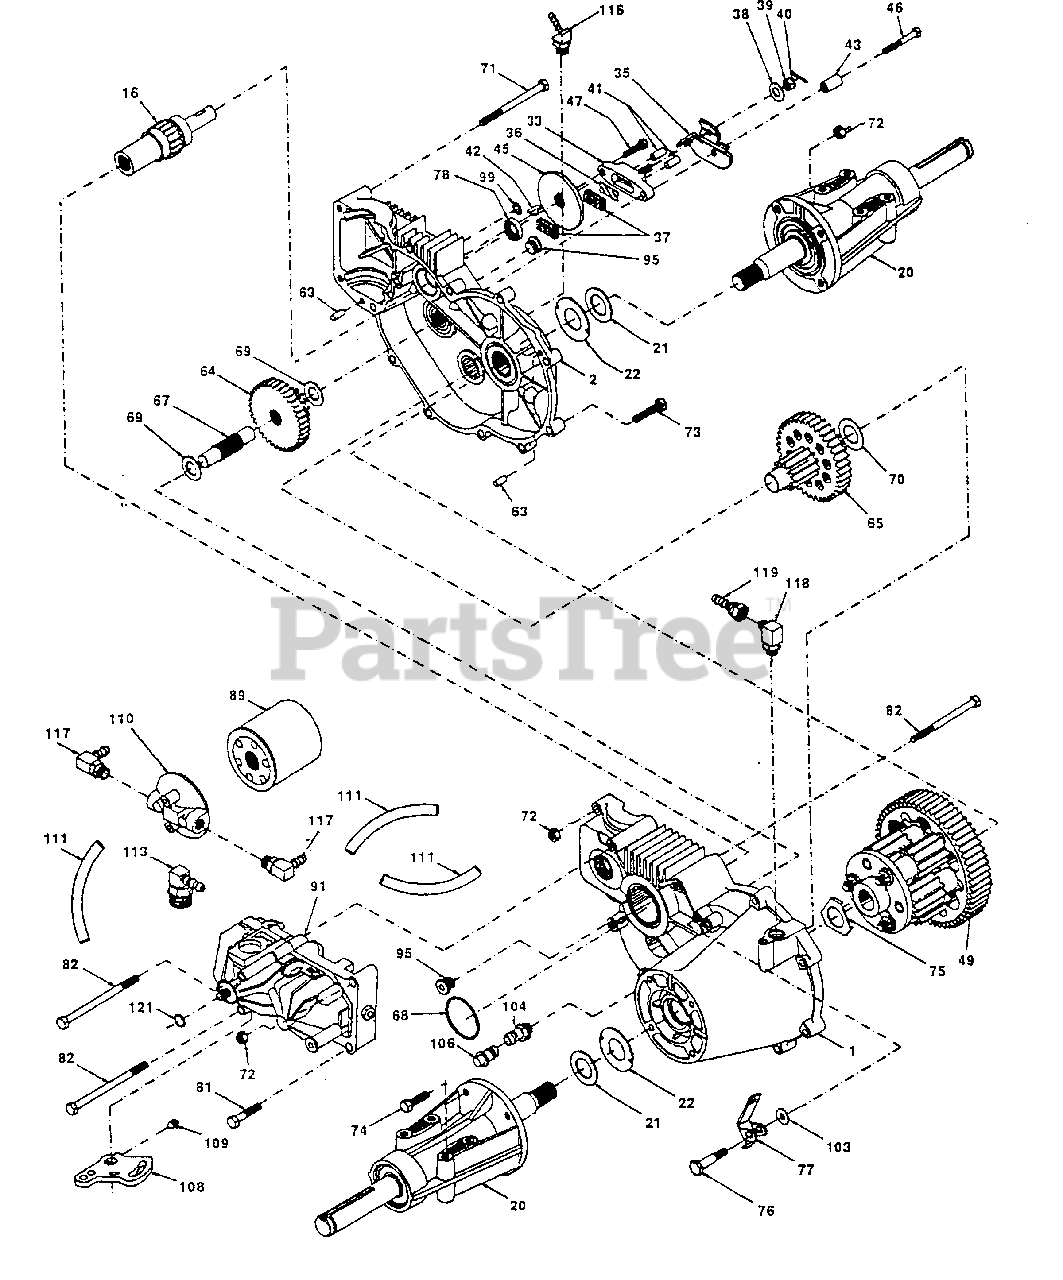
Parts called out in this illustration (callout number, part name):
1	Assembly, Lh Housing (AYP part number)
2	Assembly, Rh Housing (AYP part number)
16	Brake Shaft Assembly (AYP part number)
20	Axle Mounting Horn Ass'y (AYP part number)
21	Washer, 1.0x1.63x.08 (AYP part number)
22	Washer, 1.0x2.06x.09 (AYP part number)
33	Brake Yoke Assembly (AYP part number)
35	Brake Arm (AYP part number)
36	Puck Plate (AYP part number)
37	Brake Puck (AYP part number)
38	Washer, 7/8odx7/16x.060 (AYP part number)
39	Castle Nut, 5/16-24 (AYP part number)
40	Cotter Pin (AYP part number)
41	Brake Actuating Pin (AYP part number)
42	Hi Pro Key (AYP part number)
43	Spacer (AYP part number)
45	Brake Disc (AYP part number)
46	Bolt, 1/4-20 X 1-1/2 (AYP part number)
47	Bolt, 1/4-20 X 1 (AYP part number)
49	Differential Assembly (AYP part number)
63	Dowel Pin (AYP part number)
64	14t-38t Reduction Gear (AYP part number)
65	Final Drive Pinion Ass'y (AYP part number)
67	Jack Shaft (AYP part number)
68	O Ring (AYP part number)
69	Washer,5/8 X 1-5/32 (AYP part number)
70	Washer,7/8 X 1-1/2 (AYP part number)
71	Bolt, Hex 5/16-18 X 3.5 (AYP part number)
72	Hex Lock Nut, 5/16-18 (AYP part number)
73	Bolt, Hex 5/16-18 X 1-1/2 (AYP part number)
74	Hex Cap Screw, 5/16-18 X 1 (AYP part number)
75	Washer, Differential (AYP part number)
76	Shoulder Bolt (AYP part number)
77	Freewheel Actuating Arm (AYP part number)
78	Oil Seal, .625 X 1.0 X .25 (AYP part number)
81	Bolt, Hex 5/16-18 X 1-3/4 (AYP part number)
82	Bolt, 5/16-18 X 4-1/2 (AYP part number)
89	Spin On Filter (AYP part number)
91	Bdu-101-118 (AYP part number)
95	Straight Thread Plug (AYP part number)
99	Washer, 11/32 X 9/16 (AYP part number)
103	Washer (AYP part number)
104	Cap-Vent Assembly (AYP part number)
106	Fitting-O Ring Assembly (AYP part number)
108	Control Arm (AYP part number)
109	Set Screw (AYP part number)
110	Filter Head (AYP part number)
111	Hose, 5/16 X 12" Long (AYP part number)
113	90ø 7/8 Sae Fitting (AYP part number)
116	45ø 9/16 Sae Fitting (AYP part number)
117	90ø 9/16 Sae Fitting (AYP part number)
118	90ø Sae #6 Flare Male Fitting (AYP part number)
119	90ø Sae #6 Flare Female Fitting (AYP part number)
121	Wire Retaining Ring (AYP part number)
